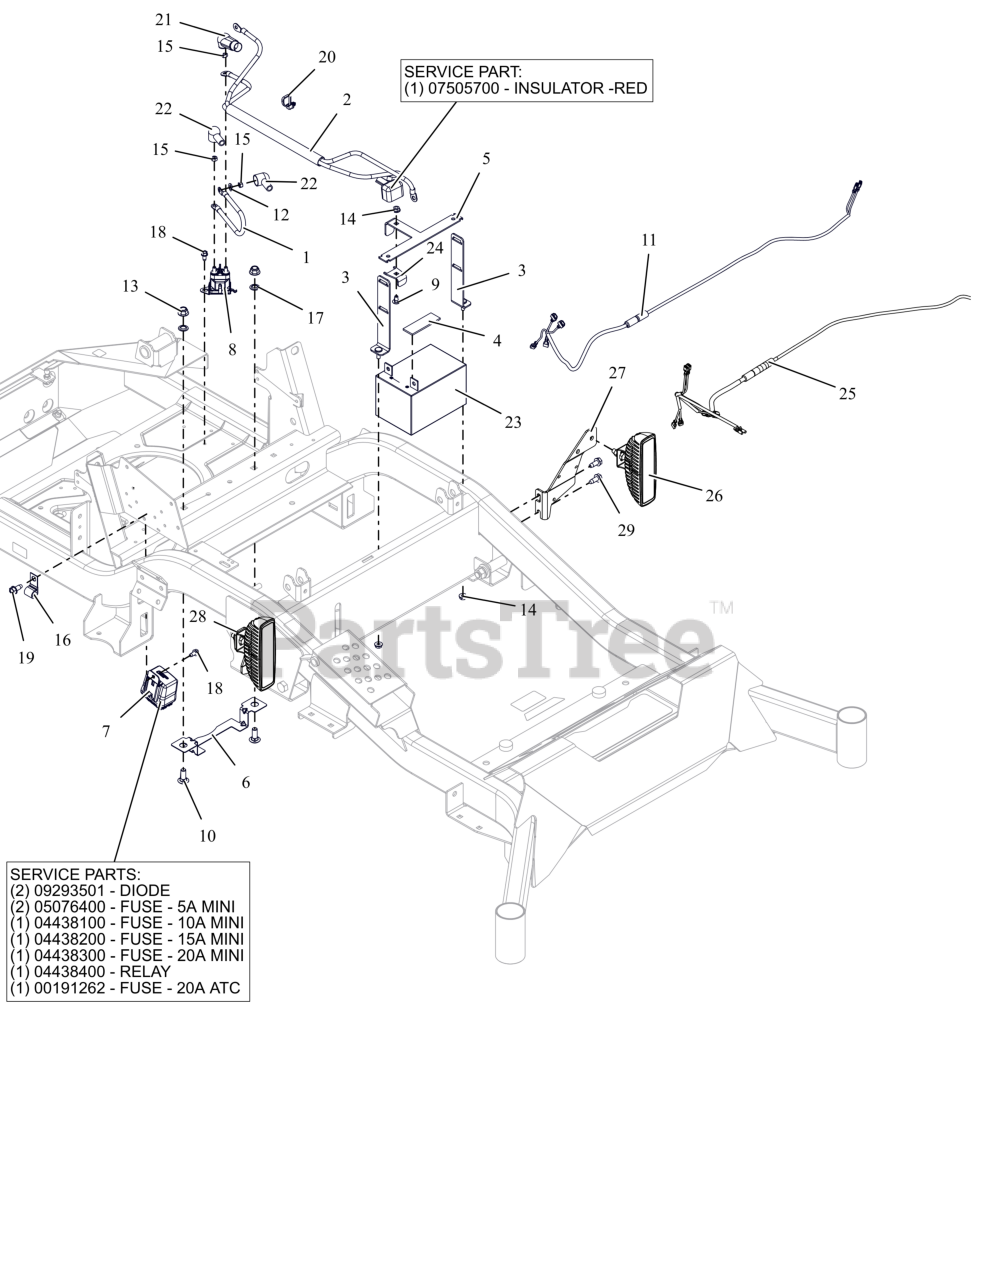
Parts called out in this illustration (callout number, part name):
1	CABLE, POS W/(2)1/4 RING 9.0LG
2	HARNESS, BATTERY HD
2	INSULATOR
3	WMT,BATTERY MOUNT HOLD DOWN
4	PAD,RBR 1.0"X3.0" W/ADHESIVE
5	BRKT, BATTERY TIE DOWN
6	GUARD, ELECTRICAL HARNESS
7	HARNESS, WIRE
7	DIODE, CONNECTOR SHELL
7	FUSE, 5 AMP MINI-ATC
7	FUSE,10 AMP MINI-ATC
7	Fuse, 15 AMP MINI-ATC
7	FUSE,20 AMP MINI ATC
7	RELAY,MICRO5 TERML W/RESISTOR
7	FUSE, 20 AMP BLADE S/O
8	SOLENOID, STARTER (SEALED)
9	BLT, RHSN .25-20X.500 G5 ZCC
10	BLT, RHSN .38-16X1.00 G5 ZCC
11	HARNESS- APEX USB PORT
12	WSHR,LK-REG .312X.078 ZCC
13	NUT,NYL-FLG .38-16 GF ZCC
14	NUT-LK-TOP-FLG .250-20 GF ZCC
15	NUT-STD M6-1.0 ZCC
16	J-CLAMP
17	NUT-PUSH .38 DIA. PAL ZINC
18	SCR-TAP .25-20X.50 HWH ZCC
19	SCR,TAP .312-18X.75 HWH TR ZCC
20	CABLE TIE W/ TREE (.25 HOLE)
21	BOOT, .65ID POS
22	BOOT, EYELET TERMINAL
23	BATTERY, 12V 12A -190CCA
24	BRKT, BATTERY HOLD
25	HARNESS, HEAD LIGHT (HD)
26	LIGHT, 6 LED W/CON.
27	BRKT, LIGHT MTG - LH (BLACK)
28	BRKT, LIGHT MTG.-RH (BLACK)
29	SCR,TAP .312-18X.75 HWH TR ZCC
